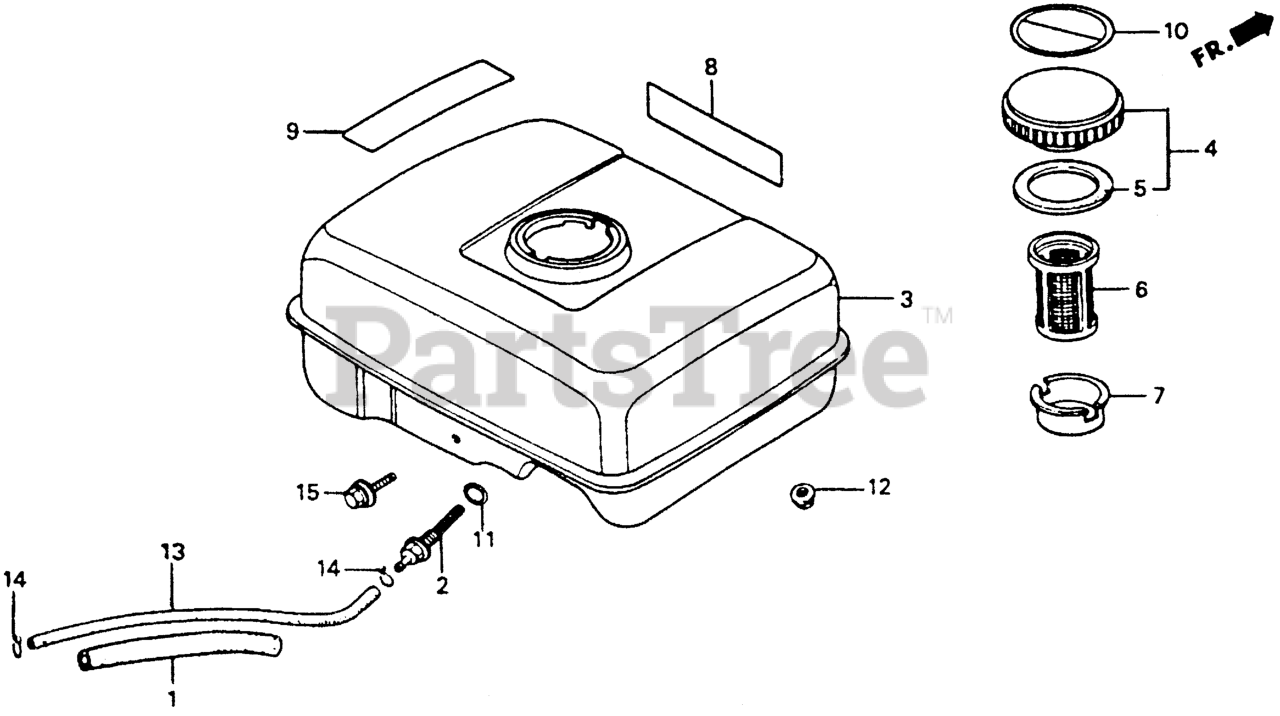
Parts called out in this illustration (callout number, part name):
1	RUBBER, SUPPORTER (107MM)
2	JOINT, FUEL TANK
3	TANK, FUEL *NH31* (MCKINLEY WHITE) Use up to Engine SN 3033315.
4	CAP, FUEL FILLER (BLACK) Use up to Engine SN 2115700.
4	CAP, FUEL FILLER (CHROME PLATED)
5	GASKET, FUEL FILLER CAP (39X58X3) (NOT AVAILABLE)
5	GASKET, FUEL FILLER CAP Use from Engine SN 1543258.
5	GASKET, FUEL FILLER CAP (39X58X3)
6	FILTER, FUEL Use from Engine SN 1370795.
7	HOLDER, FUEL FILTER
8	MARK (WB30X)
9	MARK, CAUTION (PUMP)
10	MARK, CAUTION (EXTERNAL)
11	O-RING (14MM) (ARAI) Use up to Engine SN 2949254.
12	NUT, FLANGE (6MM)
13	BULK HOSE, FUEL (4.5X3000) (Honda Code 5137104). (4.5X140)
14	CLIP, TUBE (B8)
15	BOLT, FLANGE (6X25)
